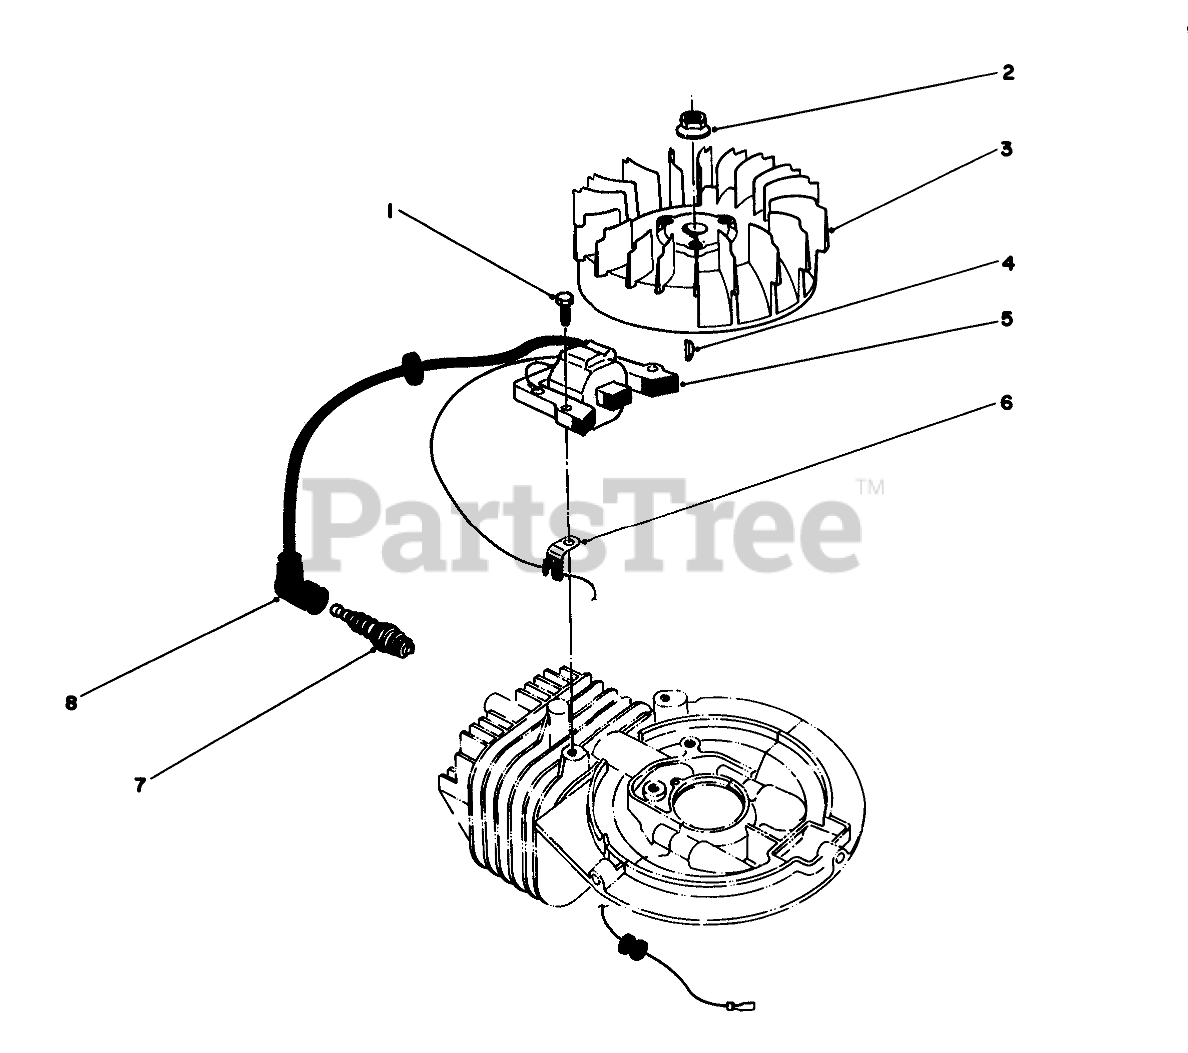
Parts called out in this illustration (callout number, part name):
1	SCREW
3	FLYWHEEL
5	COIL-MAGNETO
6	CLAMP
7	Sparkplug
8	CAP-SPARKPLUG
